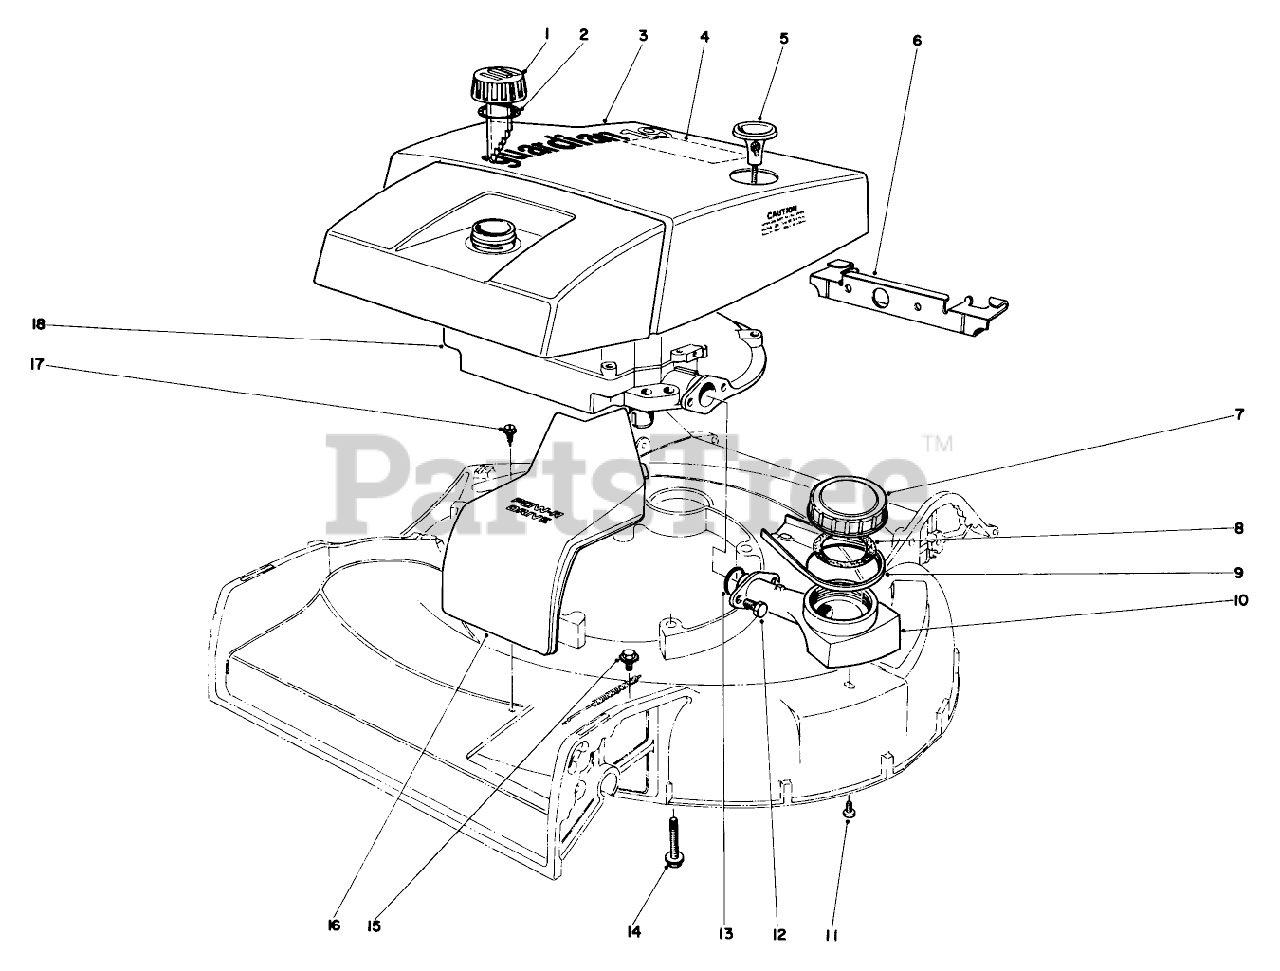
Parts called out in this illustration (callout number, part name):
2	Gasket
3	Shroud
4	Decal-Maintenance
6	Shroud Bracket
10	Oil Gauge
12	SCREW-HH
13	O RING
14	3/8-16 X 2-3/4 CAPSCR
16	Belt Drive Cover
17	SCREW-HWHTF
18	Engine
